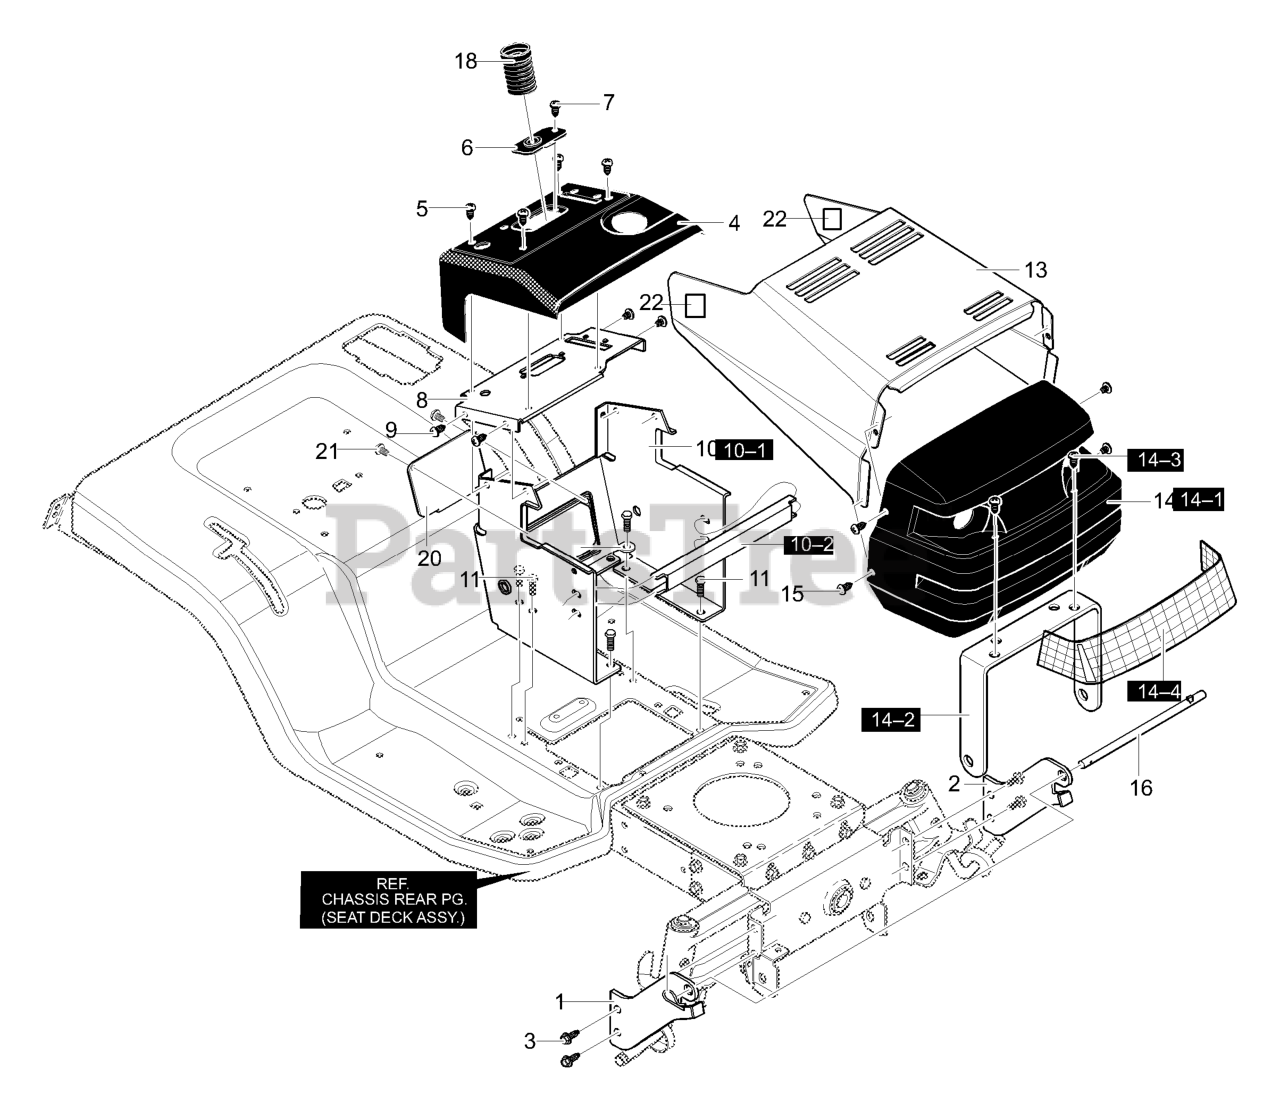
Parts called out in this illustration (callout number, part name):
1	BRACKET, Grille RH
2	BRACKET, Grille LH
3	SCREW, 5/16-18 x 0.75
5	SCREW, 10-24x.500
6	BEARING, for Dash
7	SCREW, 1/4-14x.75
8	DASH PANEL PLATE
9	SCREW, 10-24x.500
10	ASSEMBLY, Lower Console Support
11	SCREW, 5/16-18 x 0.75
14	GRILLE, Assembly
16	ROD, Hood Pivot
17	HAIR PIN
18	Bellows, Steering
19	WASHER, Bel
20	PANEL, Access
21	SCREW 10-24x.500
22	Adhesive Pad
